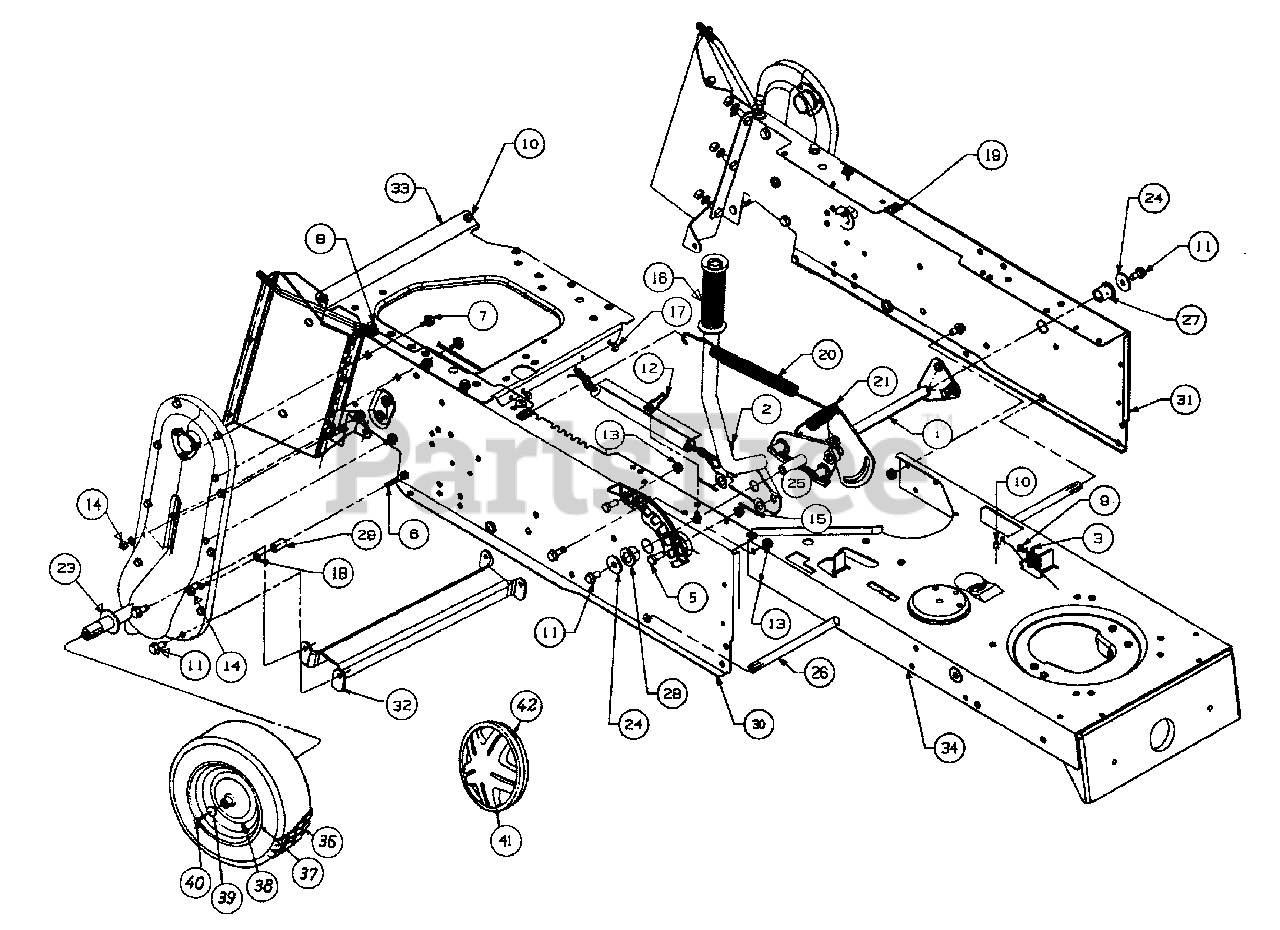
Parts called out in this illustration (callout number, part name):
2	Deck Lift Handle Ass'y.
3	Switch Plate
5	Hex Bolt 5/16-18 x .75" Lg.
6	Hex Bolt 1/4-20 x 1.5" Lg.
7	Hex Wash. Hd. B-Tap Scr. 5/16" x 1/2" Lg.
8	Hex Wash. Hd. AB-Tap Scr. 5/16-18 x .75" Lg.
9	Hex Wash. AB-Tap Scr. #10 x .5" Lg.
10	Hex Wash. Hd. Tap Scr. 1/4-20 x .5" Lg.
11	Hex Wash. Hd. SF-TAp Scr. 5-16/18 x .5" Lg.
12	Speed Nut
13	Hex Sems Nut 5/16-18 Thd.
14	Hex Sems Nut 1/4-20 Thd.
15	Cotter Pin 1/8" Dia. x 1.25" Lg.
16	Grip
17	Cable Tie
18	Push Nut
19	Speed Nut #10 Thd.
20	Deck Spring 11.1" Lg.
21	Ext. Spring 3.63" Lg.
23	FL-Wash. .76" I.D. x 1.49" O.D.
24	Fl-Wash. .344" I.D. x 1.125" O.D.
25	FL-Wash. .531" I.D. x .93" O.D.
26	Running Board Rod
27	Flange Bearing .632" I.D.
28	Flange Bearing .63" I.D.
29	Spacer
33	Transaxle Mounting Plate
38	Air Valve
39	Bell-Wash. .345" I.D. x .88"
40	Hex Bolt 5/16-24 x .75" Lg.
41	Hub Cap (Gray)
42	Spring Clip
